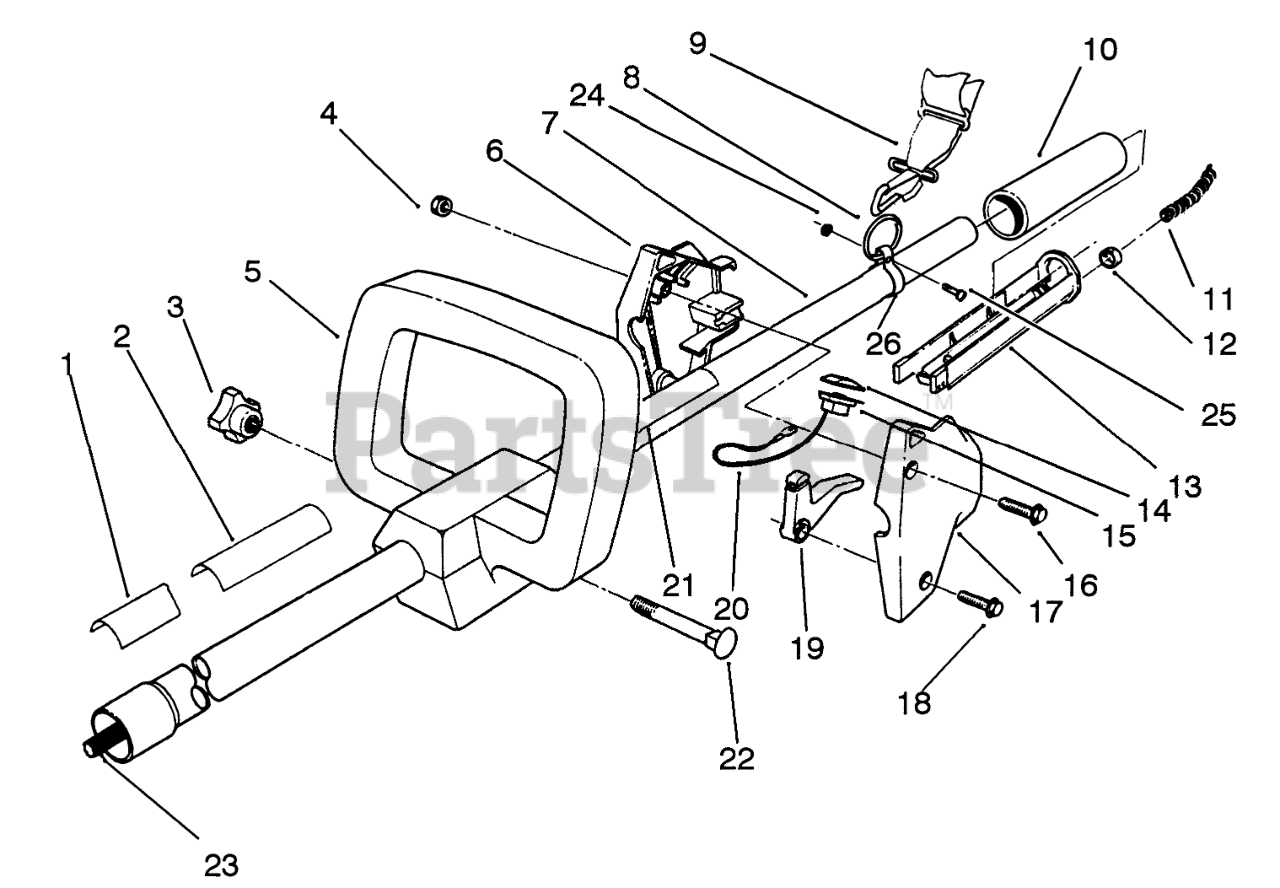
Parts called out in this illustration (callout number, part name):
1	DECAL - TC3100
2	DECAL - WARNING
4	NUT-LOCK, NI
5	HANDLE SECONDARY
6	RH HOUSING
7	TUBE ASSEMBLY
8	RING-HARNESS
9	Harness-Shoulder
10	GRIP - RUBBER
11	CABLE COVER
12	RING FITTING
13	TROUGH 1"
14	SWITCH COVER
15	SWITCH
17	LH HOUSING
18	SCREW-SHOULDER
19	THROTTLE LEVER
20	WIRE ASM
21	DECAL-INSTRUCTION
22	BOLT-CARRIAGE
23	SPLINE SHAFT
24	NUT-LOCK, NI
25	SCREW-SRH
26	HARNESS CLAMP
